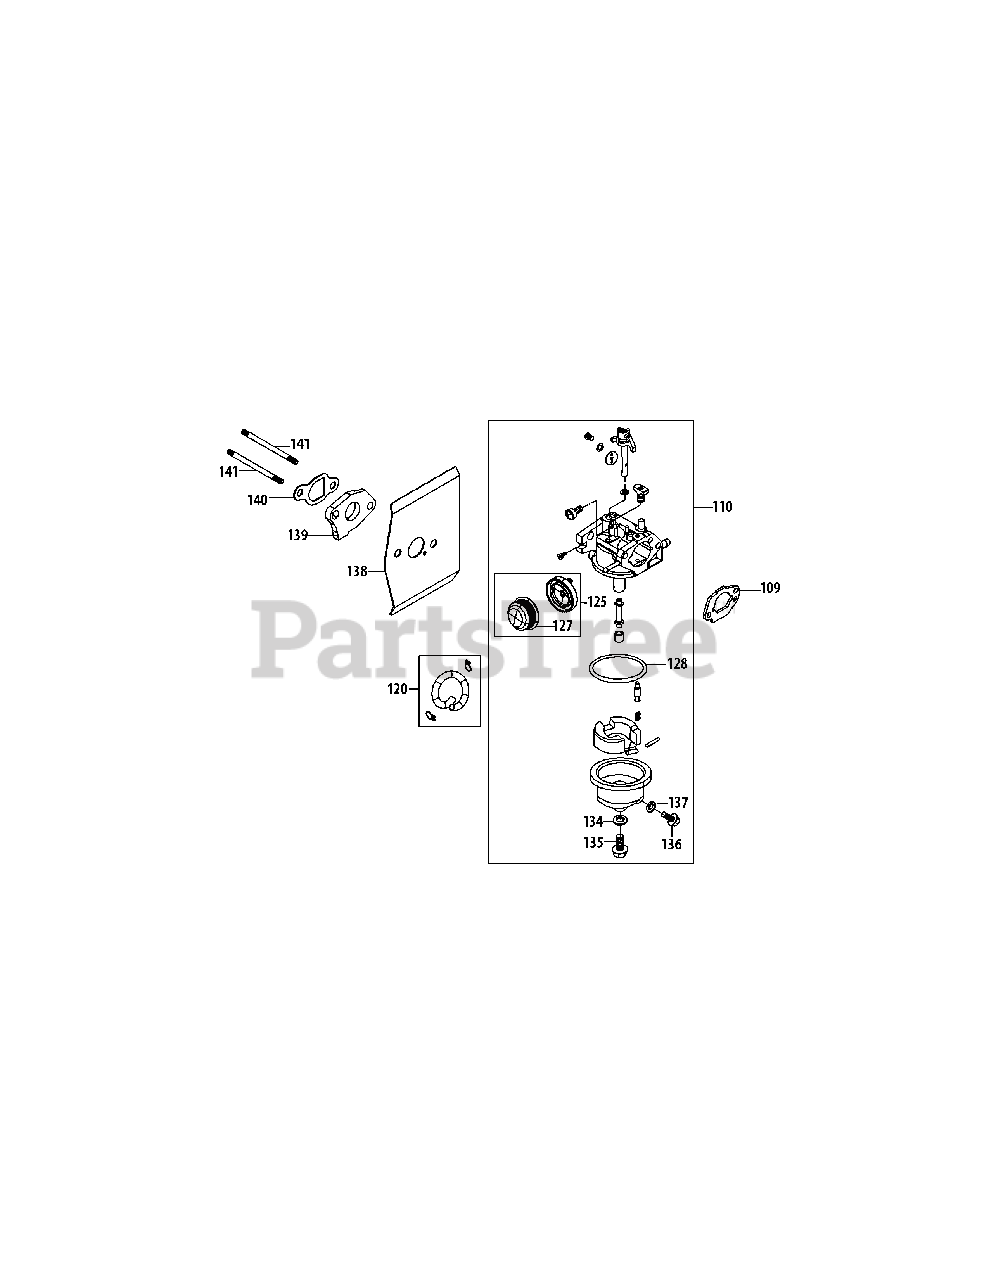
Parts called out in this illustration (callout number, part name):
109	Carburetor Gasket Plate
110	Carburetor Assembly
120	Primer Hose Assembly
125	Primer Assembly
127	Primer Bulb
128	Fuel Bowl O-Ring
134	Fuel Bowl Gasket
135	Fuel Bowl Mounting Bolt
136	Fuel Drain Plug
137	Fuel Drain Plug Gasket
138	Carburetor Gasket
139	Carburetor Insulator
140	Carburetor Insulator Gasket
141	Carb Stud M6X92
